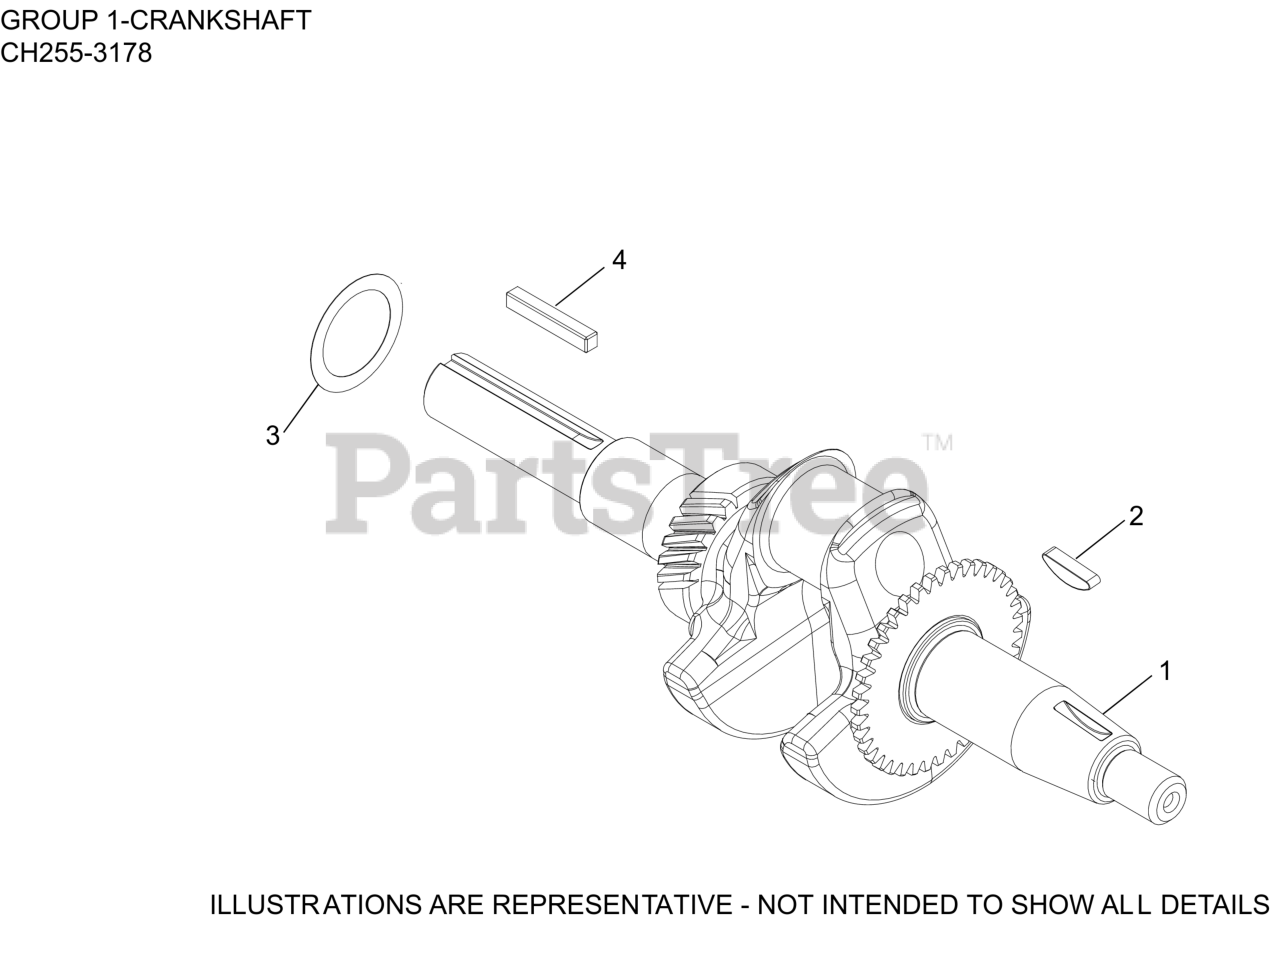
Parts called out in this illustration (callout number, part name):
1	CRANKSHAFT, ASSEMBLY
2	KEY, FLYWHEEL
3	KIT, THRUST SHIM
4	KEY, SQUARE
